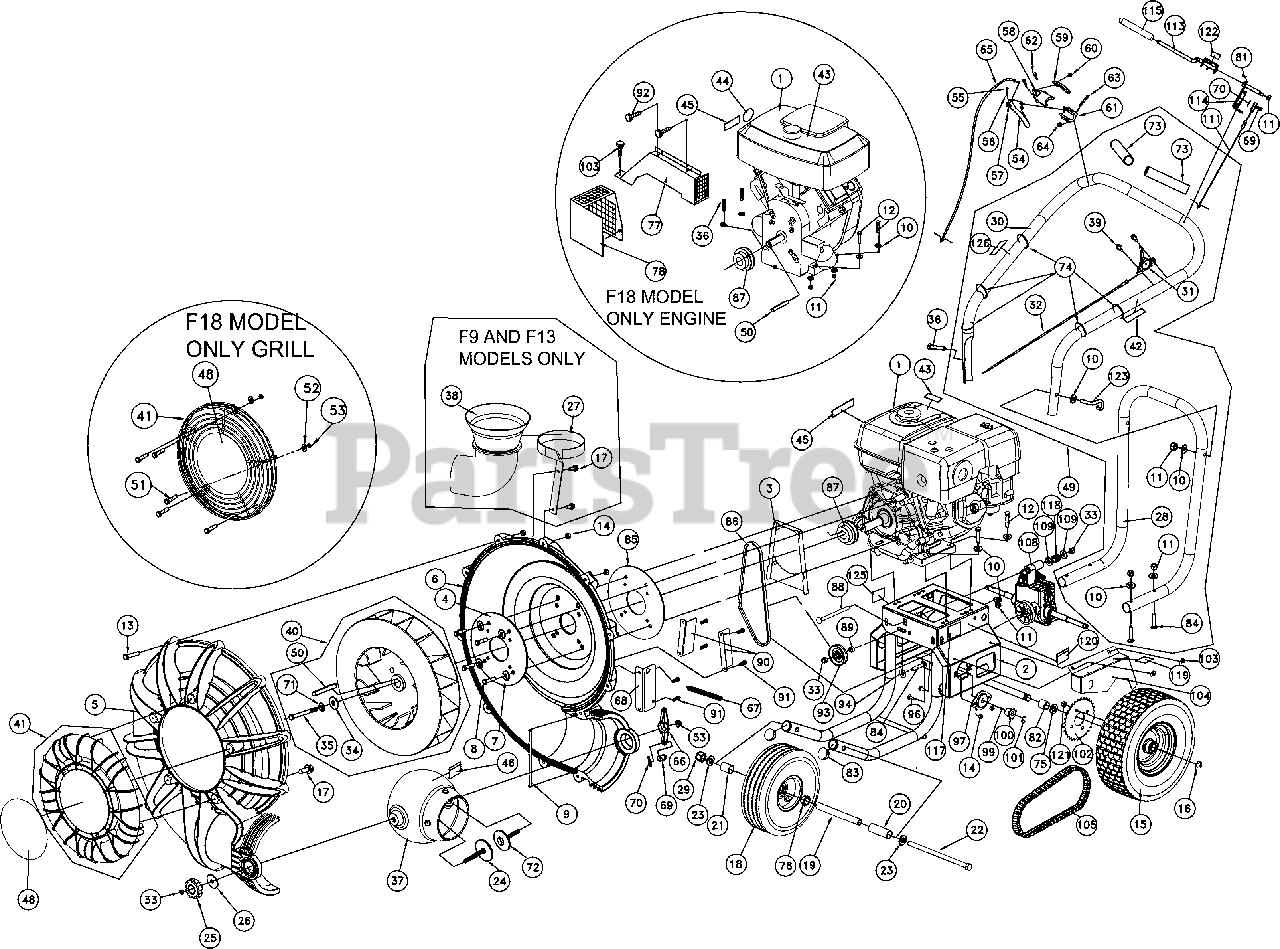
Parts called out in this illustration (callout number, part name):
1	ENGINE 9 HP HONDA GX270
2	BASE ENGINE WA FSP
3	GUARD BELT UPPER FSP
4	PLATE REINFORCE HOUSING
5	HOUSING FRONT MOLDED
6	HOUSING BACK MOLDED
7	WASHER LOCK 3/8 S/T MED
8	SCREW CAP 3/8-16X 2 ZP
9	ROD HAND STOP
10	WASHER 5/16 FLATWASHER Z/P
11	NYLON INSERT LOCKNUT 5/16-18
12	SCREWCAP 5/16-18 X 1.75 ZP
13	SCREWCAP 1/4-20 x 1 1/2
14	NUT FLANGE 1/4-20
15	WHEEL & TIRE 13" X 5" PNEUMATIC SPROCKET
16	RING RETAINING 3/4
17	SCREW SM 1/4" X 3/4" TYPE AB HX WF
18	WHEEL ASSY 10 " PNEUMATIC
19	SPACER FRONT AXLE
20	SPACER LH WHEEL FRONT
21	SPACER RH WHEEL FRONT
22	SCREWCAP 1/2-13 x 9 1/2"
23	WASHER FLAT 1/2" SAE
24	WASHER W/BOLT WA
25	KNOB 3/8-16 SOLID HUB
26	WASHER 2.25 OD x .515 ID x .134 ZP
27	BRACKET HOLDER WA
28	HANDLE LOWER
29	NYLON INSERT LOCKNUT 1/2-13LT WT TH ZP
30	HANDLE UPPER
31	CONTROL THROTTLE
32	CABLE THROTTLE CONTROL
33	NUT LOCK 3/8-16 LT WT THIN ZP
34	WASHER 1.5 O.D.X 0.45 I.D. X 0.5
35	SCREWCAP 7/16-20 X 3.5 GR.8 (60 +/-2 ft-lbs)
36	SCREWCAP 5/16"-18 X 2" ZP
37	DIRECTOR CONE 4"
38	DIVERTOR FRONT
39	SCREW SM #10-24X1/2" DRILL POINT
40	IMPELLER ASSEMBLY 17"
41	GRILL FRONT BLOWER
42	LABEL THROTTLE CONTROL
43	LABEL FUEL EN/SP
45	LABEL SAFETY PROTECT READ MANUAL
46	LABEL DANGER FLYING DEBRIS
48	LABEL FORCE
49	HANDLE ASSY
50	KEY 1/4" SQ x 3 1/4
51	SCREWCAP 1/4-20 X 1" HCS ZP
52	WASHER FLAT 1/4
53	NUT LOCK 1/4"-20 HEX ZP
54	HANDLE DIVERTER FORCE
55	PIN LATCH DIVERTER
56	SPRING COMPRESSION 0.281 X 0.88
57	RING RETAINING .122 DIA
58	SADDLE LOWER DIVERTER
59	PLATE LOCK DIVERTER
60	SCREW PLASTITE #6-19 X 5/8"
61	SADDLE UPPER DIVERTER
62	SCREW PLASTITE #10-14 X 1"
63	PIN PIVOT DIVERTER CONTROL
64	RING RETAINING 5/16
65	CABLE ASSY
66	DIVERTER PIVOT ADAPTOR
67	SPRING EXTENSION 0.468 X 5.25
68	BRACKET DIVERTER FORCE
69	PIN CLEVIS 1/4 X 3/4
70	HITCH PIN CLIP .051 X 3/4"
71	WASHER LOCK 7/16 S/T MED
72	ADAPTOR MOUNT WA
73	GRIP 1-1/4" ID x 9.5" LONG
75	WASHER .765 ID X 1.25 OD X0.6"
76	FORCE WHEEL BEARING .751 ID
77	GUARD MANIFOLD
78	GUARD MUFFLER
82	SPACER REAR WHEEL SP
84	CARRIAGE BOLT 3/8"-16 X 1 3/4" ZP
85	SPACER ENGINE FACE
86	BELT 3L29
87	SPACER HUB 1" ID X 1.25" W/PULLEY
88	CARRIAGE BOLT 3/8-16 X 5" ZP
89	TUBE SPACER .625" OD X .357 LONG
90	GUARD BELT LOWER FSP
91	SCREW PLASTITE 1/4-10 X 3/4 HWH ZP
92	BOLT 1/4"-20 X 1/2" SER FLANGE
93	PULLER V IDLER 2.5
94	WASHER 1.00" OD X .380 SQ HOLE
96	CARRIAGE BOLT 1/4"-20 X 3/4"
97	BEARING 1/2" STEEL PRESSED HOUSING
99	KEY WOODRUFF 1/8" X 1/2"
100	SPROCKET 8 TOOTH
101	RETAINING RING 1/2"
102	SPROCKET 32T #43 1.594 BORE
103	SCREW SELF TAP 1/4"-20 X 5/8"
104	CHAIN GUARD LH
104	CHAIN GUARD RH
105	CHAIN #43X44 PITCHES
108	TRANS SINGLE SPEED W/CLUTCH
109	WASHER 3/8" SAE
111	CLUTCH CABLE FORCE SP
113	CLUTCH CONTROL ARM
114	CLUTCH CONTROL BRACKET
115	GRIP CLUTCH CONTROL FSP
117	SPARK ARRESTOR LABEL
118	SPRING LEVER GZ
119	LABEL OIL CHAIN
120	LABEL DANGER
121	NUT LOCK 5/16-24 SER HEX WSHR FLNG
122	LABEL CLUTCH DRIVE
123	EYEBOLT PIGTAIL 5/16"-18 X 1 1/4"
125	LABEL MADE IN U.S.A.
126	LABEL AIM AND SHOOT
